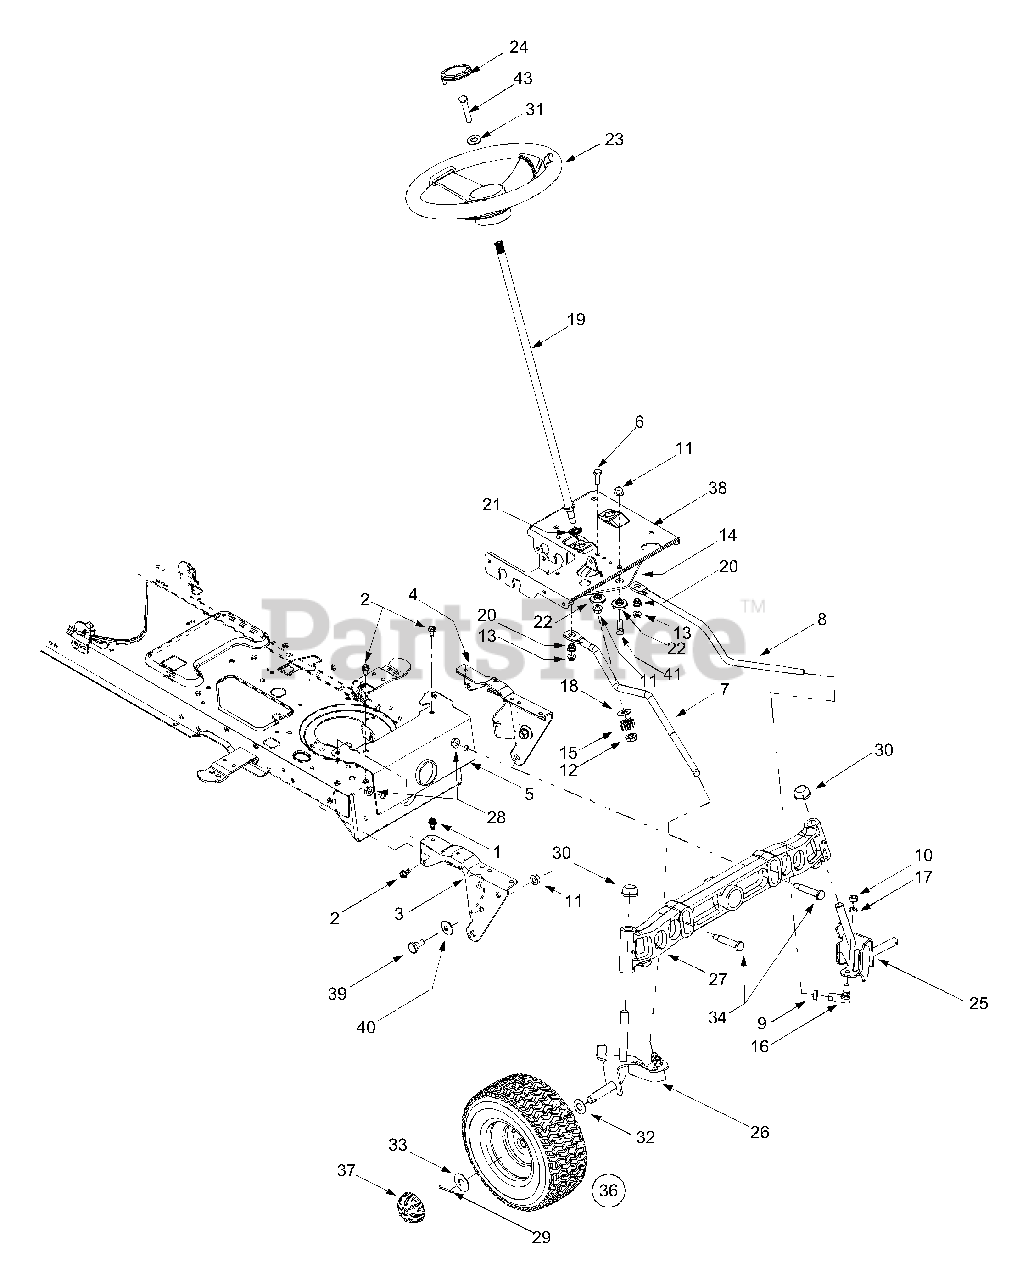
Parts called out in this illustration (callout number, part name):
1	Self-tapping Screw, 5/16-18 x .75
2	Self-tapping Screw, 16-18 x .625
6	Hex Cap Screw, 3/8-16 x 1 (Grade 5)
7	RH Drag Link
8	LH Drag Link
9	Jam Nut, 7/16-20 (Grade 2)
10	Hex Nut, 3/8-24 (Grade 2)
11	Flange Lock Nut, 3/8-16
12	Flange Lock Nut, 7/16-20
13	Flange Lock Nut, 5/16-18
14	Steering Gear, 11/90 Ratio
15	Steering Pinion Gear
16	Ball Joint, 7/16-20
17	Lock Washer, 3/8
18	Flat Washer, .51 x 1.12 x .06
19	Steering Shaft, .625 OD x 24.4
20	Plastic Bushing, .38 ID
21	Hex Flange Bearing, 5/8
22	Shoulder Spacer, .38 ID
23	Steering Wheel, Three Spoke, Soft Grip
23	Steering Wheel, Three Spoke
24	Steering Wheel Cap, Round w/logo
24	Steering Wheel Cap, Round
25	LH Axle Assembly, .75 Diameter
25	LH Axle Assembly
26	RH Axle Assembly, .75 Diameter
26	RH Axle Assembly
27	Cast Iron Pivot Bar w/ Fittings, .75
28	Flange Lock Nut, 3/8-16
29	Cotter Pin
30	Push Cap, .750
31	Bell Washer, .34 x .872
32	Flat Washer, .78 x 1.59 x .06
33	Flat Washer, .635 x 1.589 x .06
34	Shoulder Screw, .5 x 2.2, 3/8-16
35	Hex Bolt, 5/16-18 X 1
36	Tire Only, Square Shoulder
37	Hub Cap
39	Shoulder Screw, 3/8-16
40	Bell Washer, .39 x 1.13 x .062
41	Hex Bolt 3/8-16 x 1.0 Special
